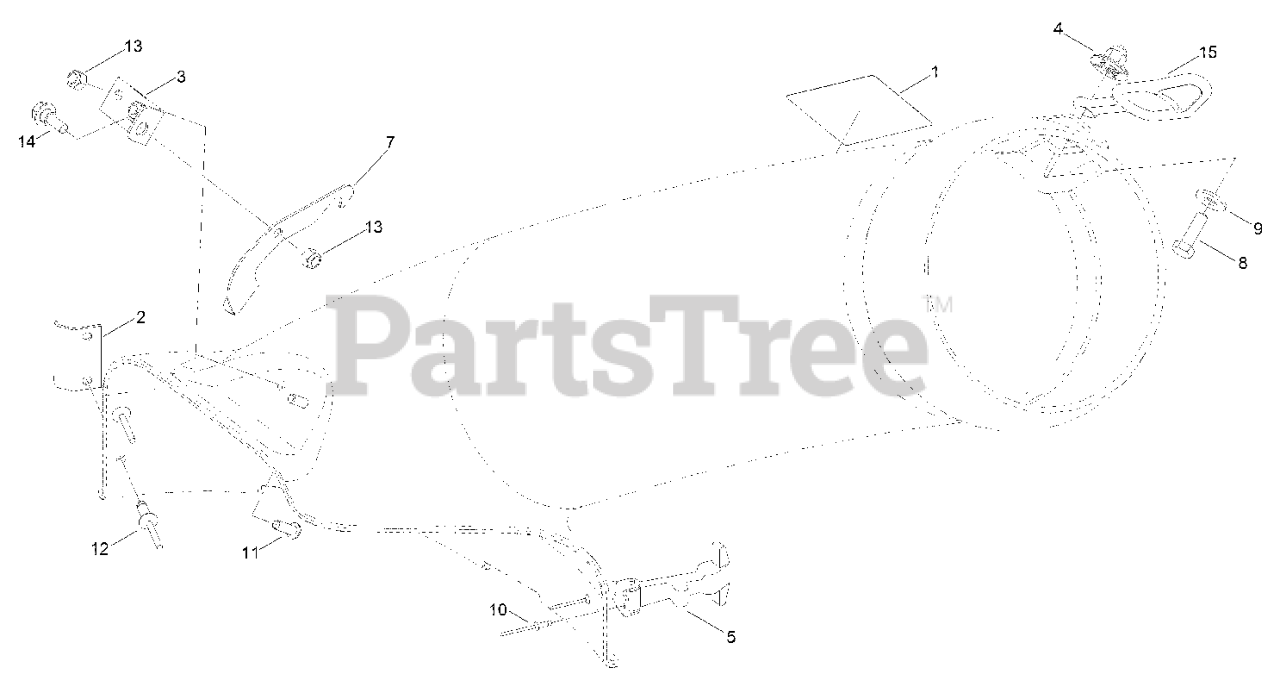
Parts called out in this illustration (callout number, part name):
1	DECAL-DANGER
2	BRACKET-ELBOW
3	PLATE-PIVOT
4	NUT-IMPELLER
5	HANDLE ASM
8	SCREW-HH
9	WASHER-FLAT
10	RIVET-POP
11	SCREW-HSBH
12	RIVET-BLIND
13	NUT-LOCK, NI
14	SCREW-SHOULDER,HWH
15	RETAINER-DUCT
